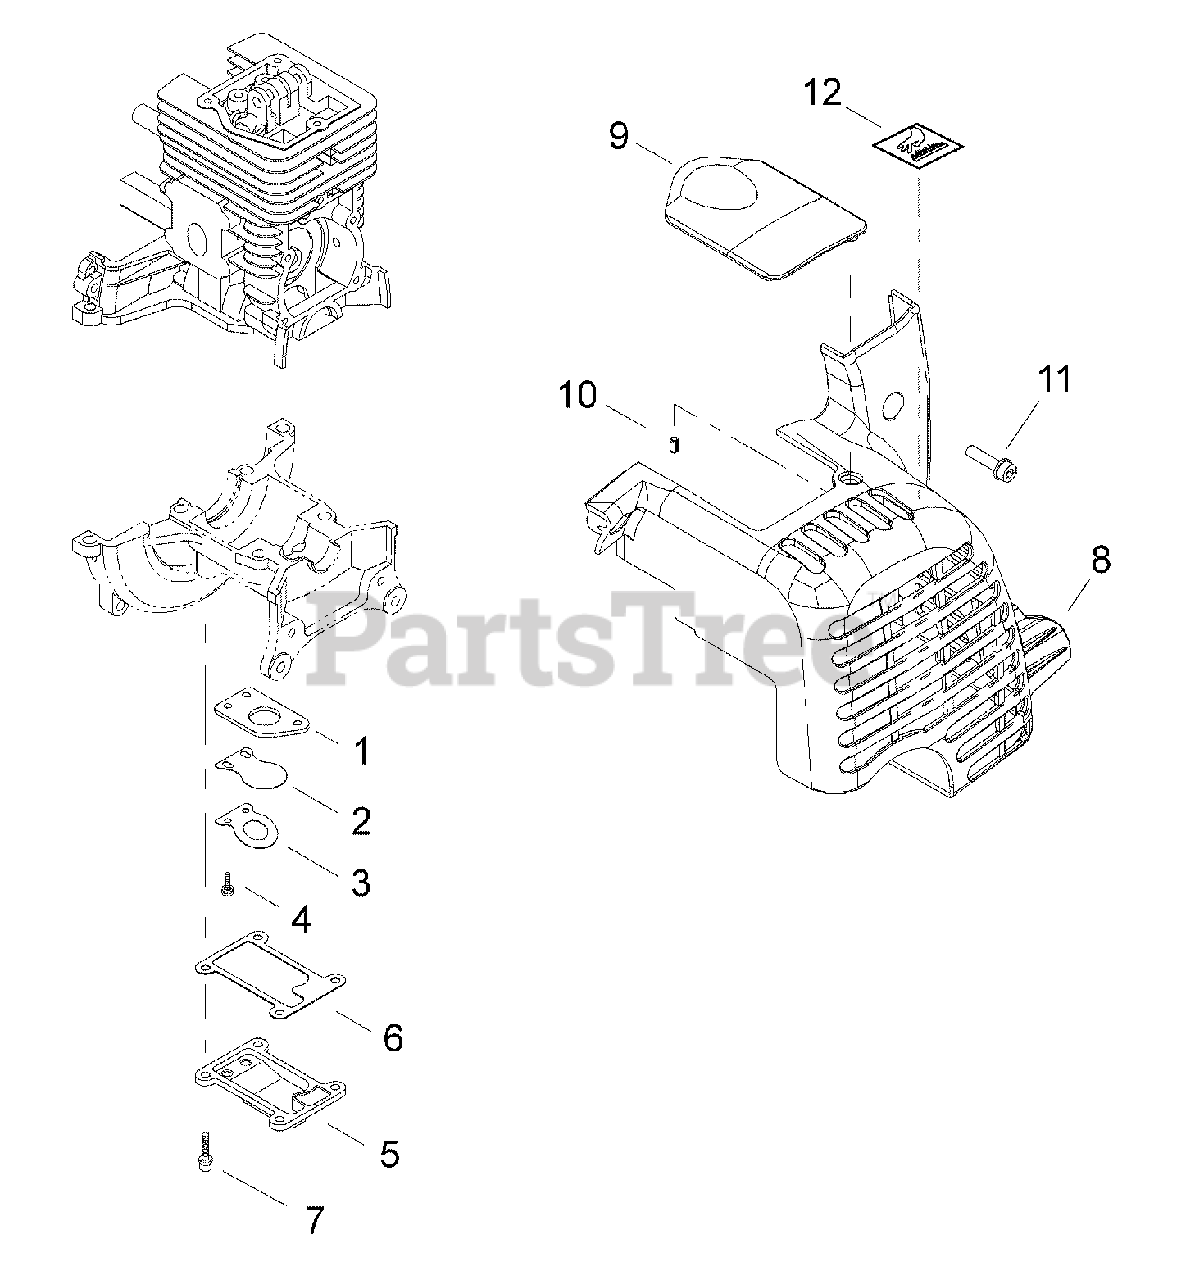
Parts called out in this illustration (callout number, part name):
1	PLATE, REED BACKING
2	VALVE, REED
3	STOP, REED VALVE
4	SCREW - 3X10
5	COVER, REED VALVE
6	GASKET, REED VALVE
7	SCREW - 4X14
8	COVER, ENGINE
9	COVER, SPARK PLUG
10	PIN - 4X8
11	BOLT - 5X20
12	LABEL - CAUTION
